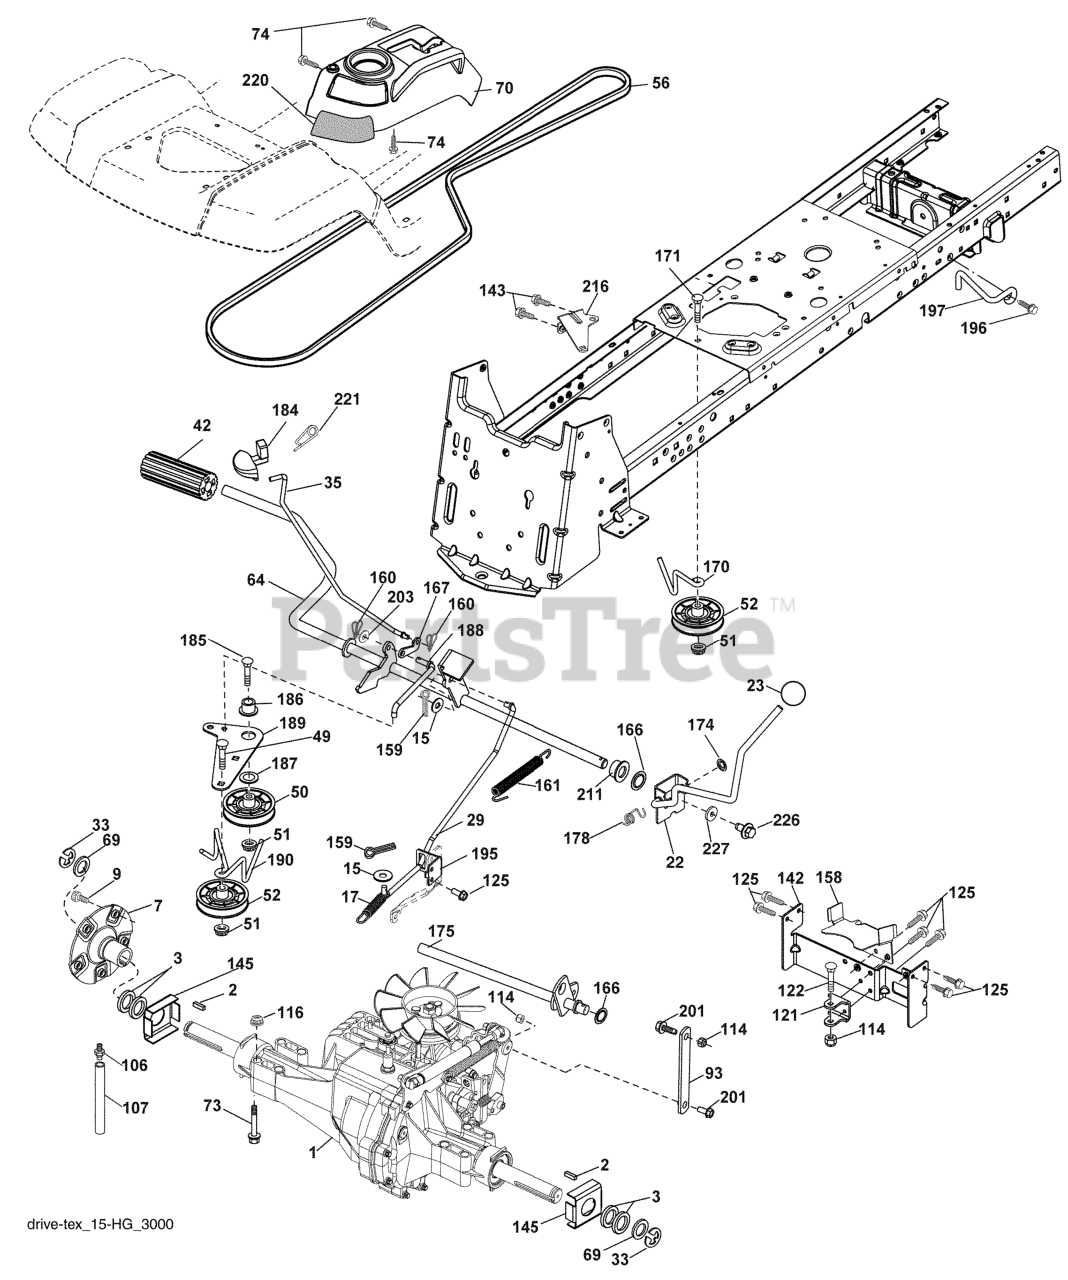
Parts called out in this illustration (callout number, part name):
2	KEY.SQUARE.187X2.500
7	HUB.ASM.WHEEL.REAR.23"TEX
9	HUB BOLT
15	WASHER
17	SPRING.BRAKE.HG3000/3500
22	SHIFTER.ASM.GT.TEX.2006
23	KNOB.DELUXE.(PISTOL.GRIP).BLAC
29	ROD.BRAKE.HG3000/3500
33	E RING HYT
35	ROD.BRAKE.PARKING.GT.H
42	PEDAL COVER T
49	BOLT
50	IDLER.FLAT.910.OFFSET
51	NUT LOCK FLG 3/8-16 UNC
52	IDLER.V-GROOVE.910.OFFSET
56	BELT.V.GROUND.DRIVE
64	SHAFT.ASM.PEDAL.BRAKE.
70	RP CONSOLE.ASM.HYDO.HUSQ.
73	BOLT HEX FLGHD 5/16-18X3 GR. 5
74	SCREW.HI-LO.CONSOLE
93	LINK.TRANSAXLE.HG3000/3500
106	CAP, VENT ASSY
114	NUT.71038.31-18.HEX.NYLOCK
116	NUT LOCK HEX FLANGE 5/16-18
121	BRACKET STRAP TORQUE
122	BOLT.5/16-18X2.5
125	SCREW
142	STRAP.TORQUE.HG3000/K46
143	Screw Thdrol 5/16-18 x 1/2
145	WASHER.AXLE.FLANGE.HG-3000
158	KEEPER BELT
159	COTTER PIN
160	RETAINER CLIP
161	SPRING.RETURN.CLUTCH.2006
166	NUT.PUSH.625.2006
167	LATCH.BRAKE.SPRING
170	KEEPER.V-IDLER.CENTER.
171	BOLT
174	NUT.PUSH.500.2006
175	SHAFT ASM SHIFT
178	SPRING.SHIFT.GT2006
184	HANDLE.PARKG.BRK.HUSQ X667
185	BOLT
186	SPACER.RETAINER
187	WASHER 12/32X2X10GA
188	RP.LINK.CLUTCH.GROUND.DRIVE
189	BELLCRANK.GROUND.DRIVE.TEX.
190	KEEPER.BELLCRANK.DRIVE
195	RETAINER.ROD.BRAKE.HG3000.TEX
196	SCREW 3/8-16X1
197	BRKT.ANIT-ROTATION.CLUTCH
200	NUT.CENTERLOCK.5/16-
201	BOLT SHOULDER 5/16-18 UNC
203	WASHER
211	BUSHING.SHAFT.BRAKE.HAND
216	BRACKET.PULLEY.IDLER.W/TEX
220	REFLECTOR.RH.TEX GT
221	RETAINER.SPRING.CLIP.H
226	BOLT FIN HEX 7/16-14 X 1
227	WASHER SERRATED
